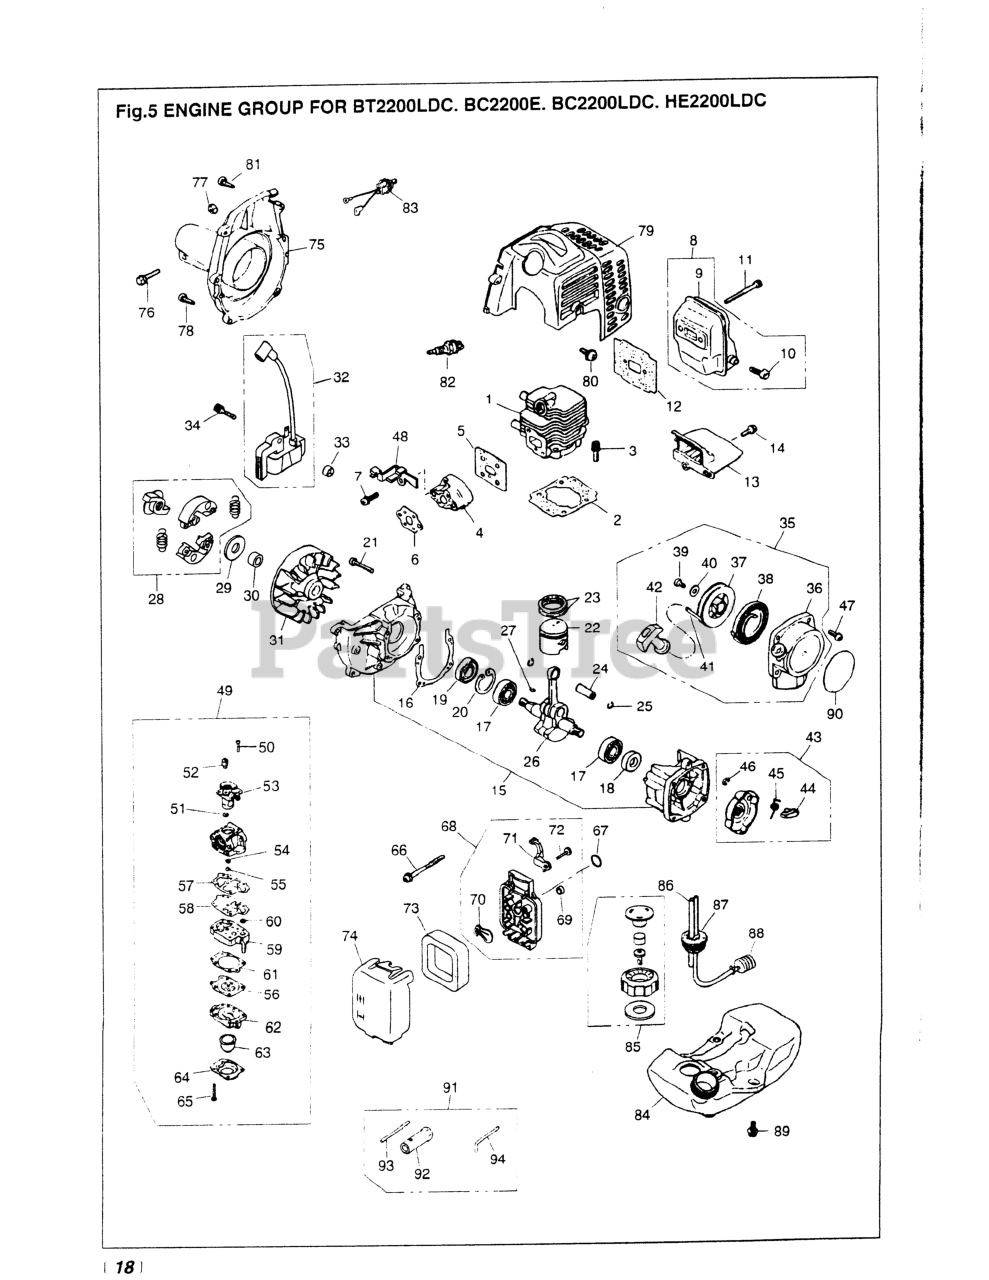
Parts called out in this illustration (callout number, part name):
1	CYLINDER
3	BOLT, M5 X 22
8	MUFFLER ASSY (RPLS 5501- )
15	CRANKCASE (NLA)
17	BEARING
18	SEAL, OIL (RPLS 1100-21210)
19	SEAL, OIL (RPLS 1140-21220)
20	RING, SNAP, M28 x 1.2
21	BOLT, M5 X 30
22	PISTON (REPLACES 1140-41110)
23	RING, PISTON (RPLS 1850-41210)
24	PIN, PISTON 5x8x26
25	RING, SNAP (RPLS 1101-41320)
26	CRANKSHAFT COMP.
27	KEY
32	COIL
33	SPACER (RPLS -71260)
40	WASHER (USE 181741)
46	RING, SNAP, M4
51	RING
52	SWIVEL
53	VALVE ASSY
54	RING, O
55	JET
56	DIAPHRAGM (USE 4810-81260)
57	GASKET, PUMP
58	DIAPHRAGM
59	BODY, PUMP
61	GASKET, DIAPHRAGM
62	BODY, PURGE
63	PUMP, PRIMING
64	COVER, PUMP
65	SCREW
69	SLEEVE
70	PLATE, CHOKE
71	LEVER
72	SCREW
76	BOLT, M6x35 (RPLS -50635)
77	NUT, M6 X 5
83	SWITCH COMP
91	TOOL SET
94	BAR
